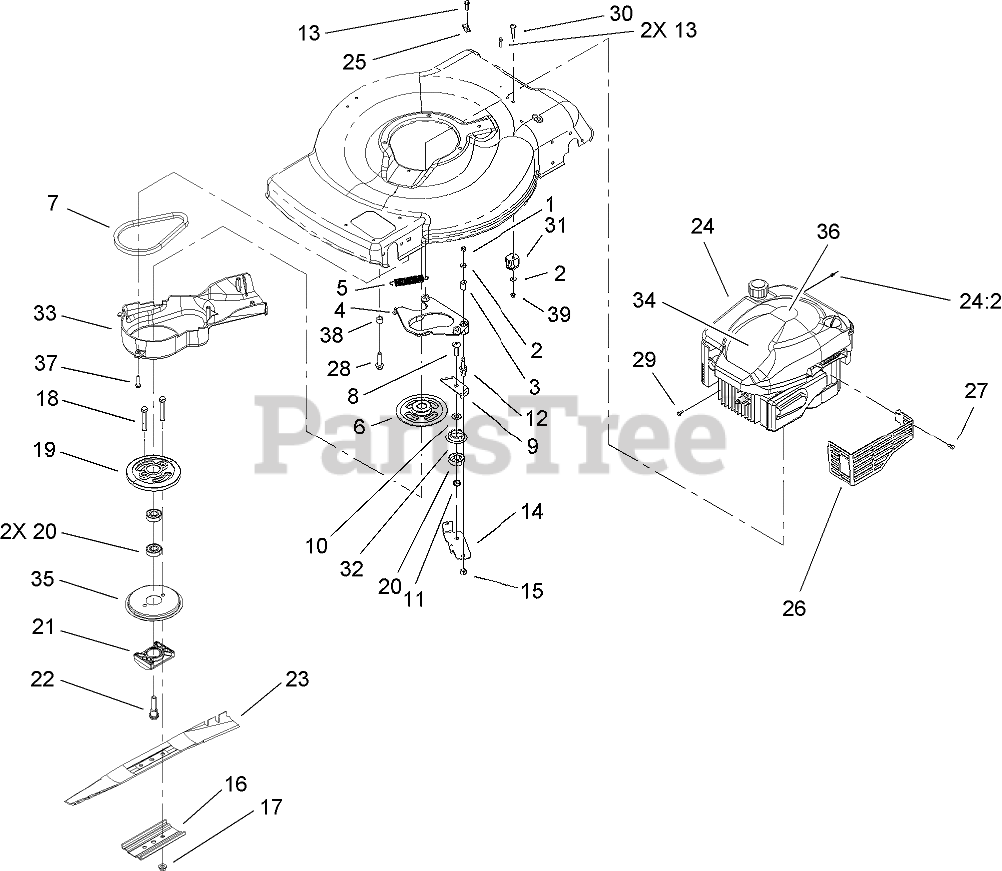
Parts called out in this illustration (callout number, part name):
1	NUT-LOCK, NI
2	WASHER-FLAT
3	BUSHING
4	PLATE-ANCHOR
5	SPRING-TENSION, BRAKE
6	PULLEY
7	BELT
8	BOLT-CARR
9	PLATE-GUIDE
10	WASHER-PLAIN
11	SPACER-BEARING
12	BOLT-SHOULDER
13	SCREW-HWH
14	BRAKE ARM ASM
16	SUPPORT-BLADE
17	NUT-LOCK
18	SCREW-HH
19	DRUM
20	BEARING-BALL
21	SUPPORT-BLADE
22	BOLT-CRANK
23	BLADE-22 INCH
24:2	STOP-ROPE
25	CLIP-CLOSED, INSULATED
26	SHIELD-MUFFLER
27	SCREW-TAPTITE
28	SCREW-HWH
29	SCREW-HWH
30	SCREW-CARR
31	ANCHOR-CABLE
32	RETAINER-BELT
33	COVER-BBC
35	DISC
36	DECAL-RECOIL
37	SCREW-PLASTITE
38	TUBE-SPACER
39	NUT-LOCK, NI
